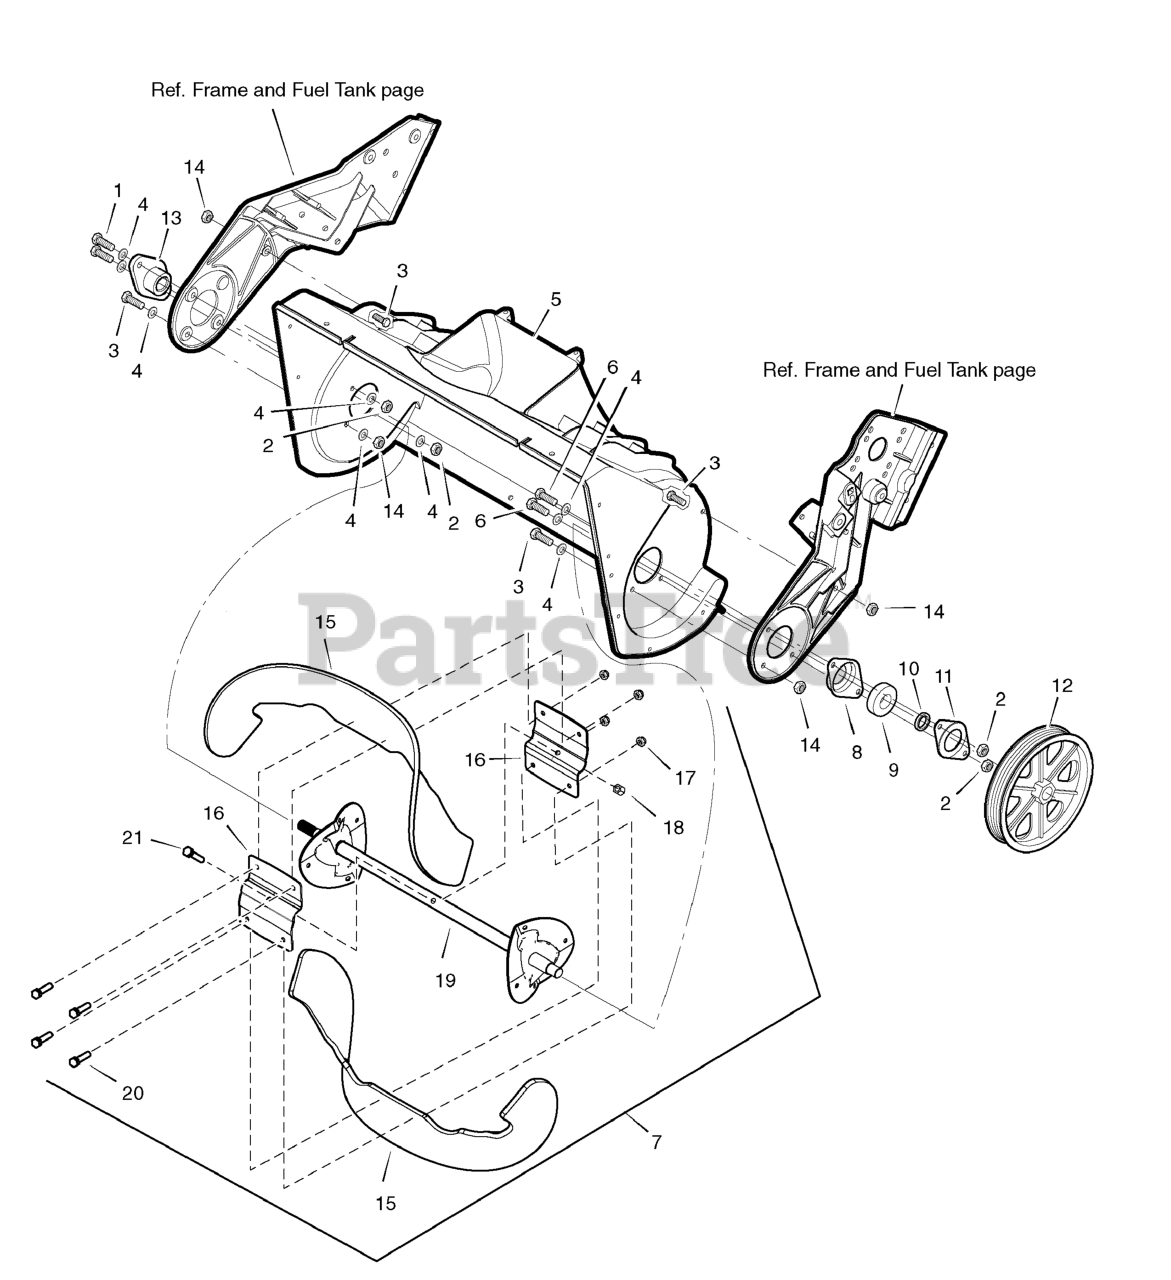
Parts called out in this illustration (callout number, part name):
1	Screw, 1/4-20 x 1.00
2	Nut, Hex 1/4-20
3	Screw, 1/4-20 x .75
4	Washer, Flat
5	Housing Assembly, Auger
6	Screw, 1/4-20 x .63
7	Auger Assembly, 22"
8	Retainer, Bearing
9	Bearing
10	Sleeve, Spacer
11	Plate, Bearing Retainer
12	Pulley, Auger Drive V6
13	Bearing, Flange
14	Nut, Centerlock 1/4-20
15	Blade, Auger. Black
16	Bracket, Center Auger
17	Nut, Nylock
18	Nut, Hex-Lock, ESNA Light, 5/16-18, NC38, Blavk
19	Shaft, Sub
21	Capscrew, Hex-Head, 5/16-x 1.5, G5 Black
